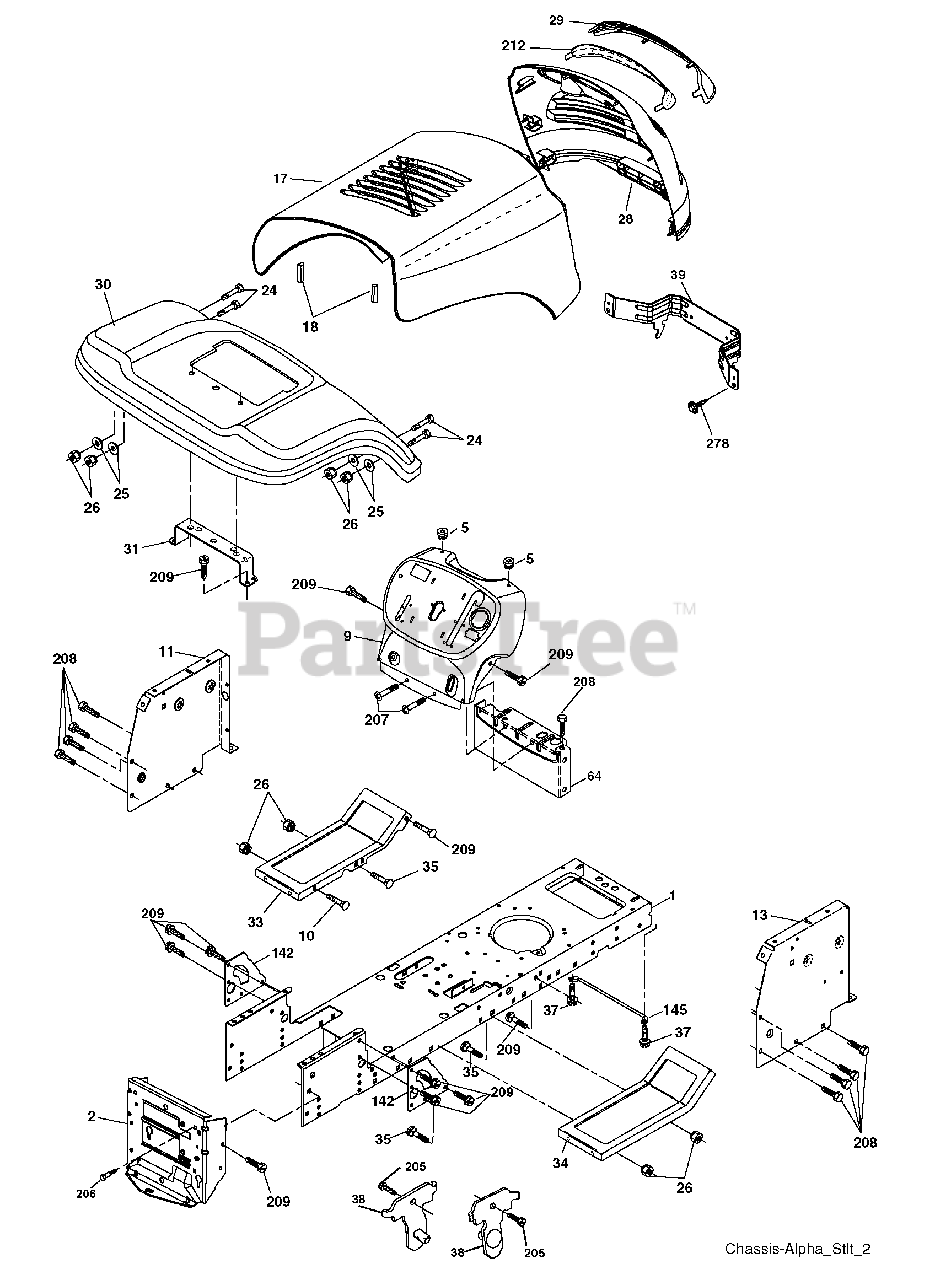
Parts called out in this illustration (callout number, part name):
1	Chassis
2	Drawbar
5	Bumper Hood/Dash
9	Dash
10	Bolt Carriage 3/8-16 x 1
11	Panel Dash Lh
13	Panel Dash Rh
17	Hood
18	Bumper Hood
24	Bolt Fin Hex 3/8-16 x 1 Gr. 5
25	Washer 13/32 x 13/16 x 12 Ga.
26	Nut Lock Hex W/Ins 3/8-16 unc
28	Grille
29	Lens
31	Bracket Support Fender
33	Footrest Pnt Lh
34	Footrest Pnt Rh
35	Bolt Rdhd Sht Sqnk 3/8-16 x 3/4
37	Screw Thdrol 6/16-18 x 1/2 TYT
38	Bracket Asm. Pivot Mower Rear
39	Bracket Pivot
64	Dash Lower STLT
142	Plate Reinforcement STLT
145	Rod Pivot Chassis/Hood
205	Screw Thdrol 3/8-16 x 1-1/4
206	Bolt Shoulder 5/16-18
207	Screw Thdrol 5/16-18 x 1/2
208	Screw Thdrol 3/8-16 x 1/2
209	Screw Hex Wsh Thdr. 3/8-16 x 3/4
212	Insert Lens Reflect
278	Screw 10 x 3/4 Single Lead-Hex
278	Plug Dome
278	Plug Btn Blk .359
